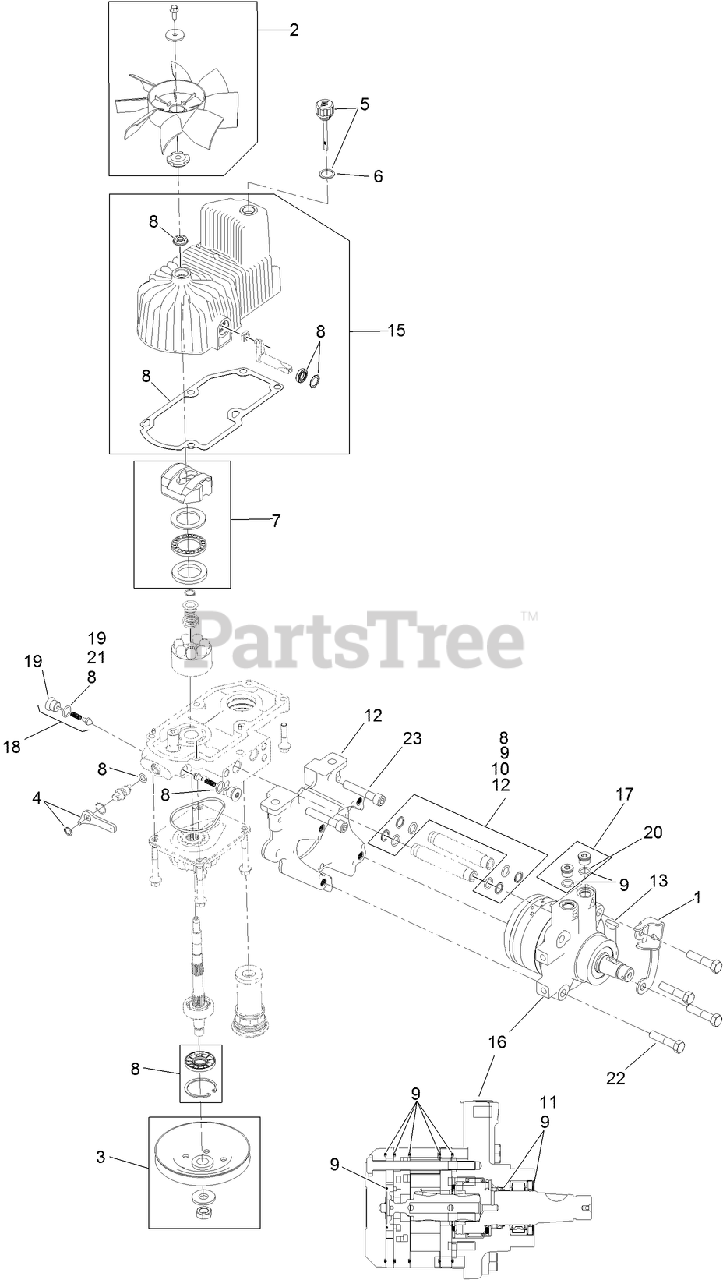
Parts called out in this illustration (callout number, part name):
1	BRACKET-ANCHOR, CABLE
2	FAN KIT
3	PULLEY KIT
4	HANDLE-BYPASS VALVE, HYDRO
5	DIPSTICK-HYDRO W/GASKET
6	GASKET-DIPSTICK, HYDRO
7	SWASH BLOCK KIT
8	PUMP SEAL KIT
9	MOTOR SEAL KIT
10	TUBE SEAL KIT
11	OUTPUT SHAFT SEAL KIT
12	NOSE CUP-UHT
13	KEY-WOODRUFF
15	Housing-RH
16	MOTOR-HYDRAULIC RH 240CC
17	MAGNETIC PLUGS SERVICE KIT
18	CHECK VALVE ASM
19	PLUG-CHECK (W/O-RING)
20	O-RING
21	O-RING-CHECK VALVE
22	SCREW HH
23	SCREW-HSH
